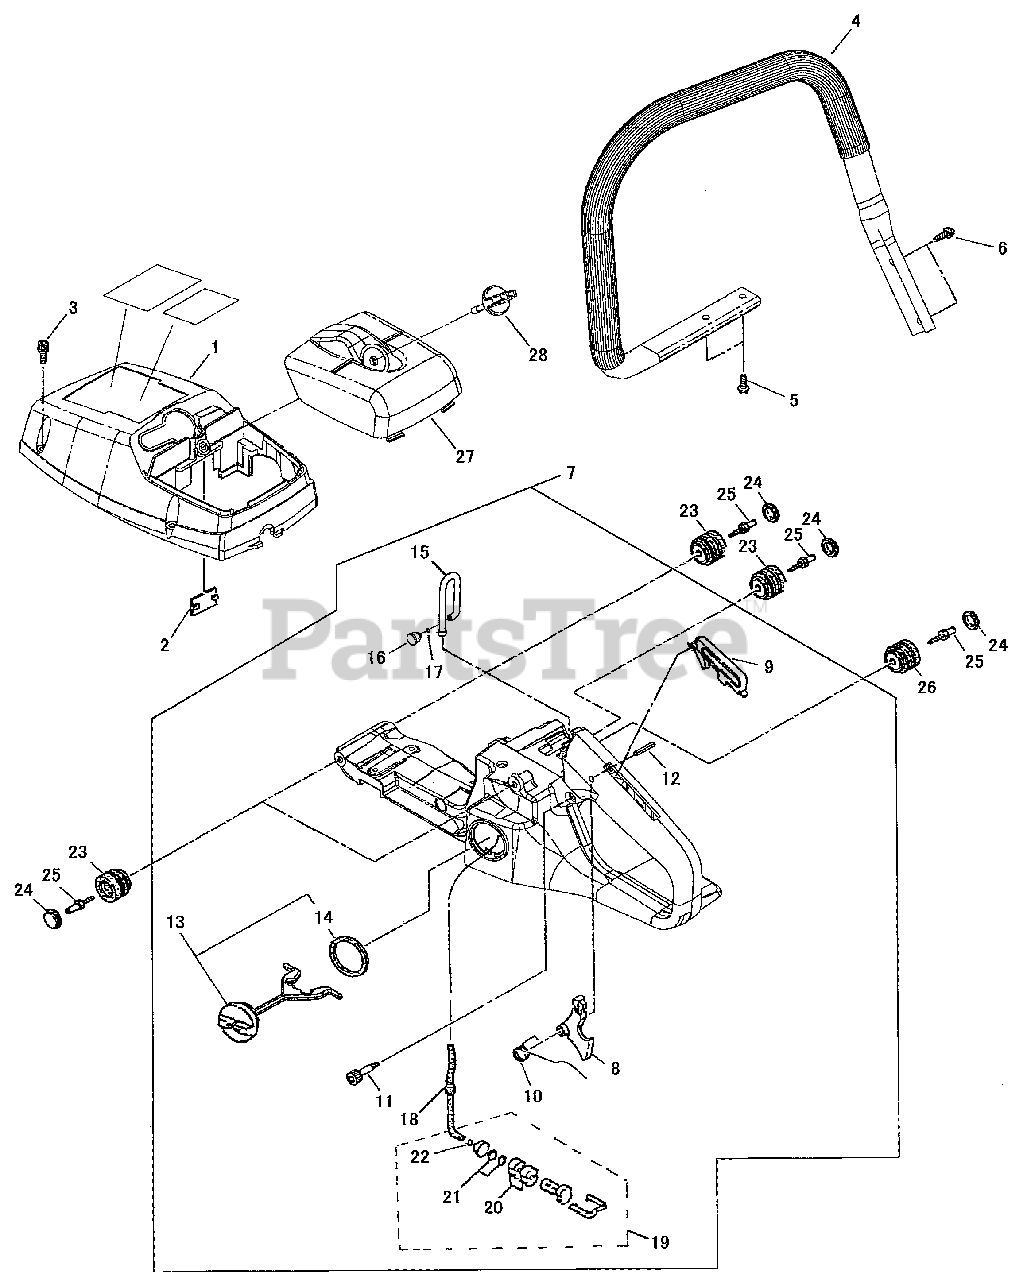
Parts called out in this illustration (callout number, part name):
1	COVER, ENGINE
2	PLUG
3	BOLT 5
4	HANDLE, FRONT
5	SCREW M5
6	SCREW 5×20
7	HANDLE ASSY, REAR
8	LEVER, THROTTLE
9	LEVER, LOCK
10	SPRING, RETURN
11	BOLT
12	PIN 4×25
13	CAP ASSY, FUEL
14	GASKET, FUEL CAP
16	VENT ASSY
17	CLIP Ø6
18	PIPE, FUEL
19	FILTER, FUEL
20	FILTER, FUEL
21	SCREEN, FILTER
22	CLIP Ø6
23	CUSHION
24	PLUG
25	BOLT 5
26	CUSHION
27	COVER, AIR FILTER
28	KNOB
